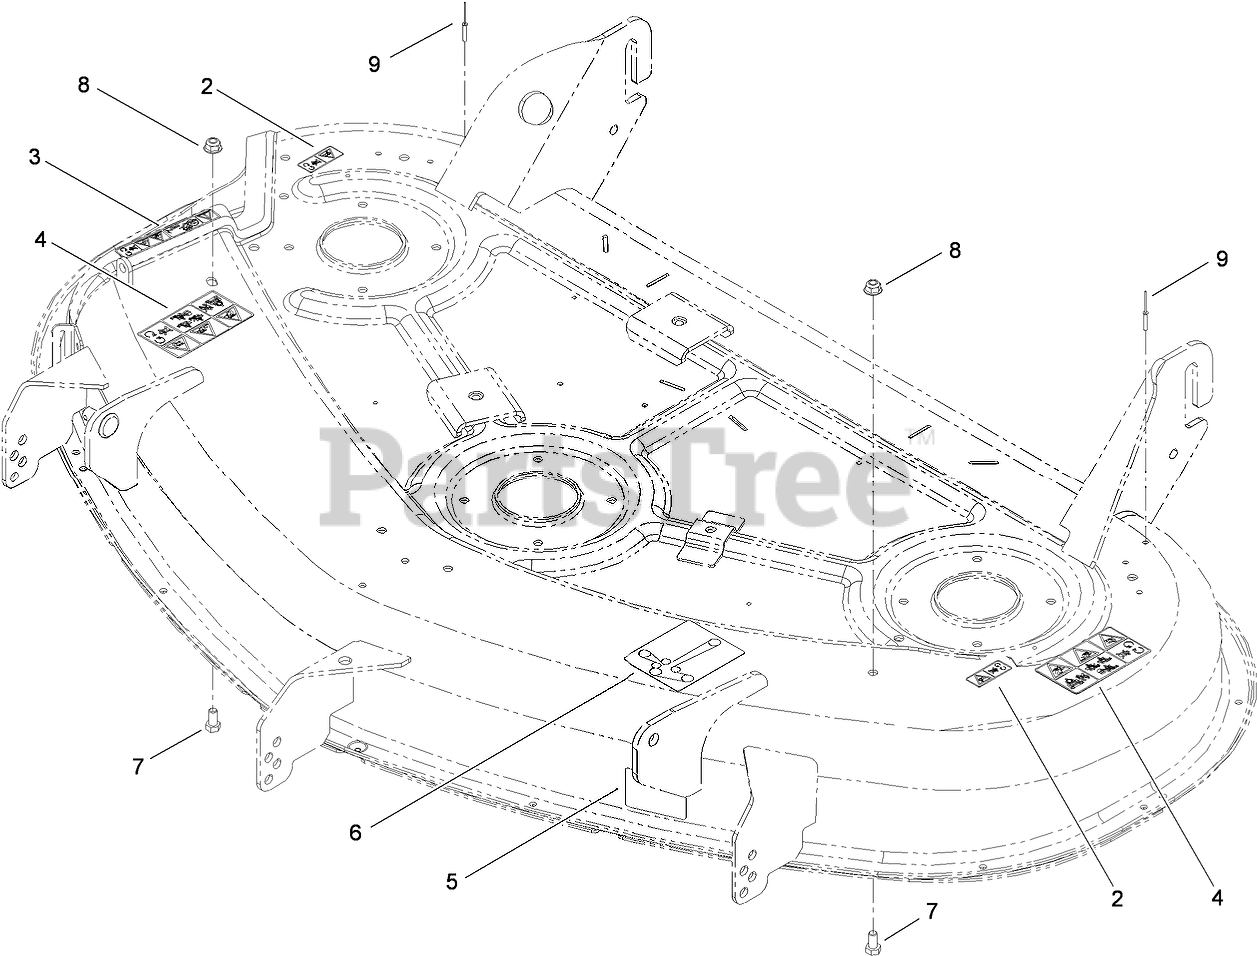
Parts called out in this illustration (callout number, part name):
2	DECAL-DANGER
3	DECAL-DANGER
4	DECAL-DANGER
5	DECAL-SCALP, ANTI
6	DECAL-ROUTING, BELT
7	SCREW-HH
8	NUT-HF, NI
9	RIVET-BLIND
